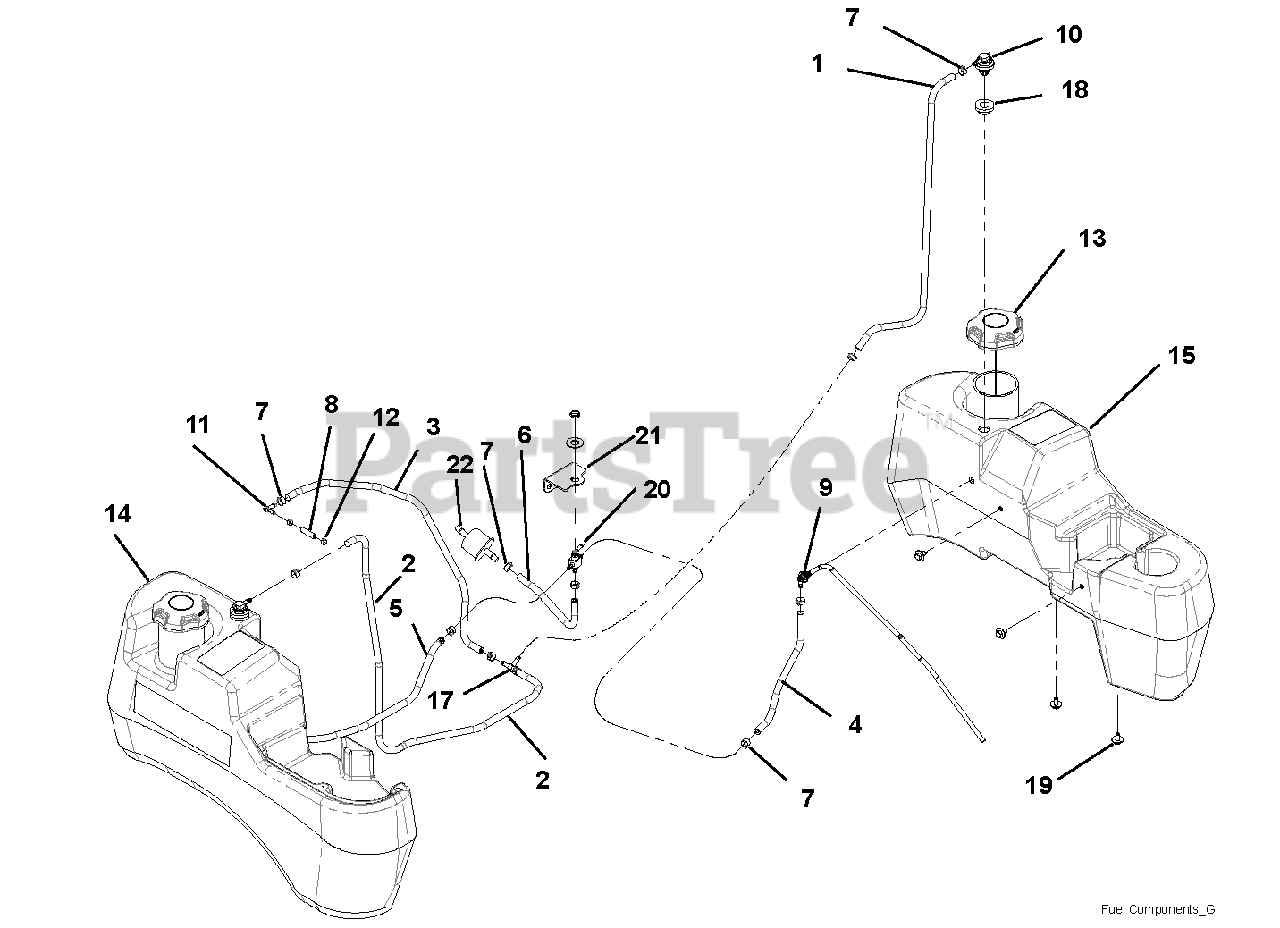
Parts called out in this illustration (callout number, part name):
1	HOSE, .25 LOW-PERM BULK GAS
2	HOSE, .25 LOW-PERM BULK GAS
3	HOSE, .25 LOW-PERM BULK GAS
4	HOSE, .25 LOW-PERM BULK GAS
5	HOSE, .25 LOW-PERM BULK GAS
6	HOSE, .25 LOW-PERM BULK GAS
7	CLAMP, FUEL LINE
8	HOSE, .188 LOW-PERM BULK GAS
9	ASS'Y, LARGE TANK FUEL PICK-UP
10	VALVE, COMBINATION
11	FITTING-3/16X1/4 90DEGREE VAC
12	CLAMP-HOSE, SPRING .188
13	CAP,3.50" VENT-IN RATCHET FUEL
14	TANK, RH LARGE FUEL W/O LOGO
15	TANK, LH LARGE FUEL W/O LOGO
16	Label, EPA Non-Compliant Tank
17	TEE,1/4HS RUN X 1/4HS BRANCH
18	GROMMET, REMOTE VENT
19	BOLT, SEMS .31-18 X .62
20	VALVE - FUEL
21	BRKT, FUEL VALVE MNTG
22	FUEL FILTER - KAWASAKI
